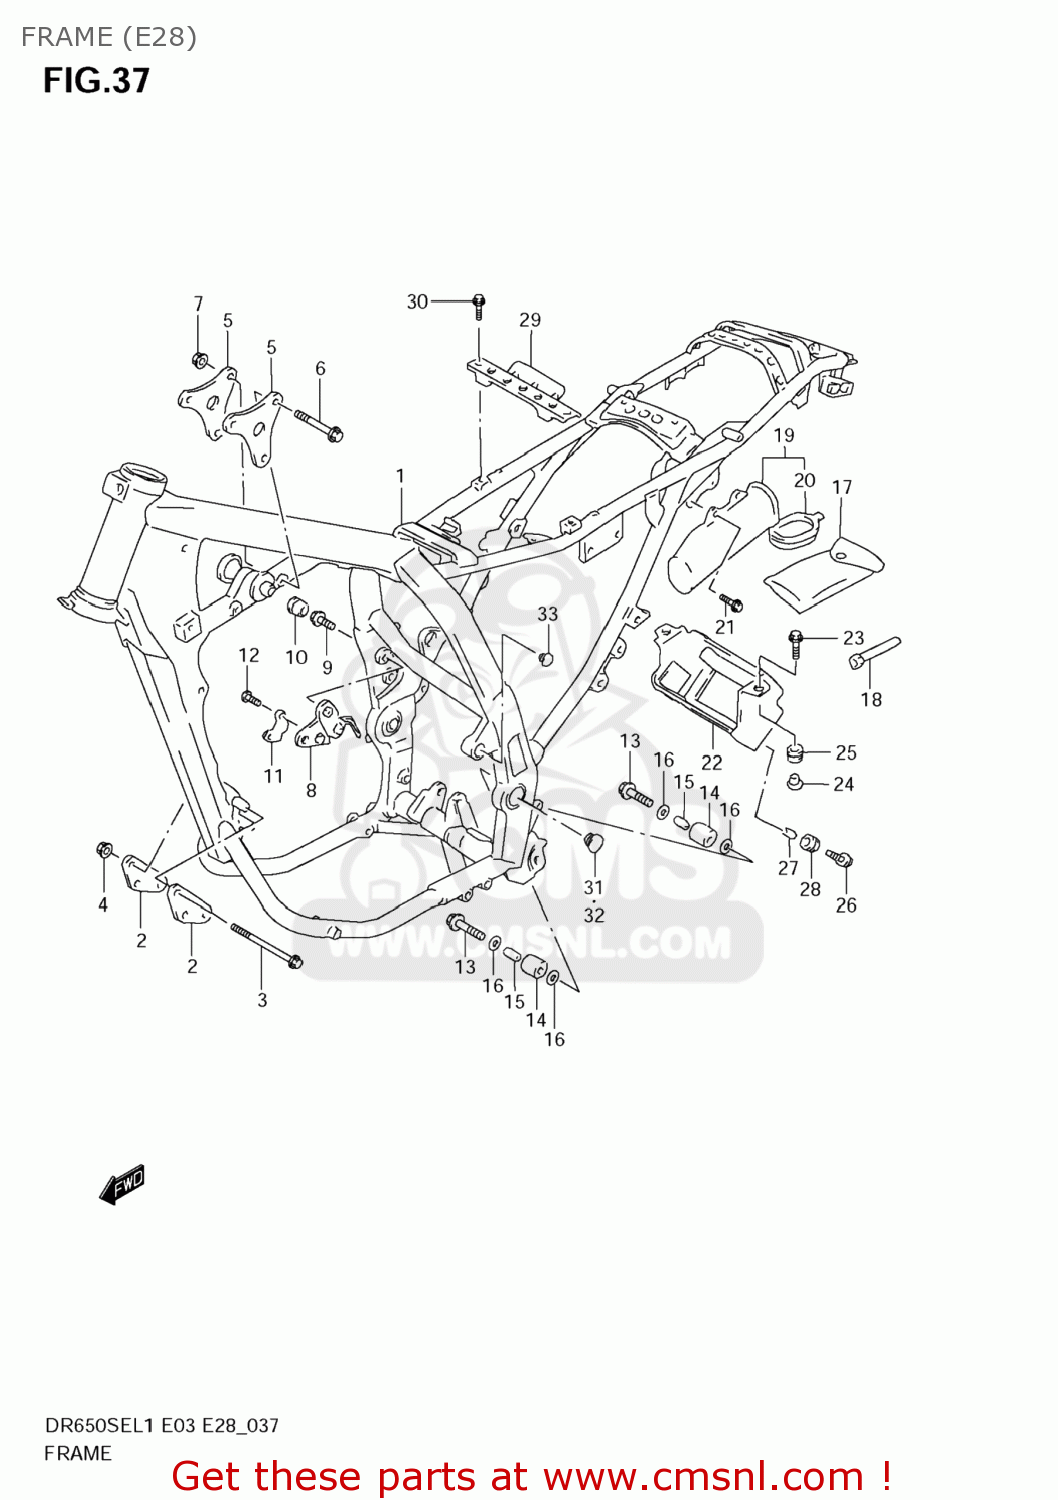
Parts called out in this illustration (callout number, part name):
1	FRAME(GRAY)
2	PLATE,ENG MTG FR
3	BOLT(8X100)
4	NUT
5	PLATE,ENG MTG UPR
6	BOLT(8X55)
7	NUT
8	PLATE,ENG MTG RR,R
9	BOLT
10	PLUG(OD:22)
11	BRACKET,STOP SWITCH
12	SCREW
13	BOLT(8X38)
14	ROLLER,CHAIN CONTROL UPR
15	SPACER(8.6X12X25.5)
16	WASHER
17	TOOL ASSY
18	SPARK PLUG WRENCH(16)
19	HOLDER,TOOL
20	CAP,HOLDER
21	BOLT(6X16)
22	HOLDER,BATTERY
23	BOLT(6X20)
24	WASHER
25	CUSHION
26	BOLT(6X16)
27	SPACER(6.1X9X7.5)
28	CUSHION
29	PLATE,BATTERY FITING
30	BOLT
31	PLUG,FRAME PIVOR,R
32	PLUG,FRAME PIVOR,L
33	PLUG,FRAME BOSS
